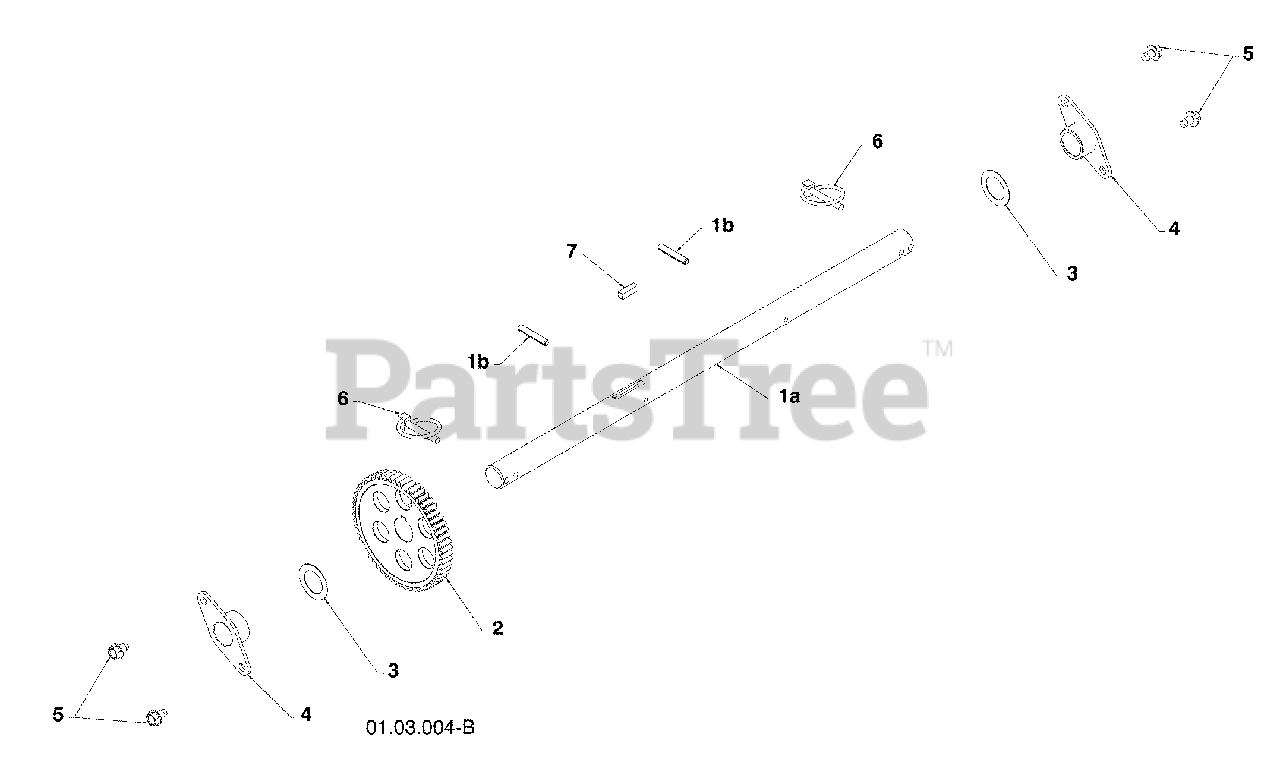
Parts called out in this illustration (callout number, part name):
1	(assy of 1a,1b) AXLE ASSEMBLY
2	GEAR
3	THRUST WASHER
5	BOLT 5/16-18 X .500
7	SQUARE KEY
